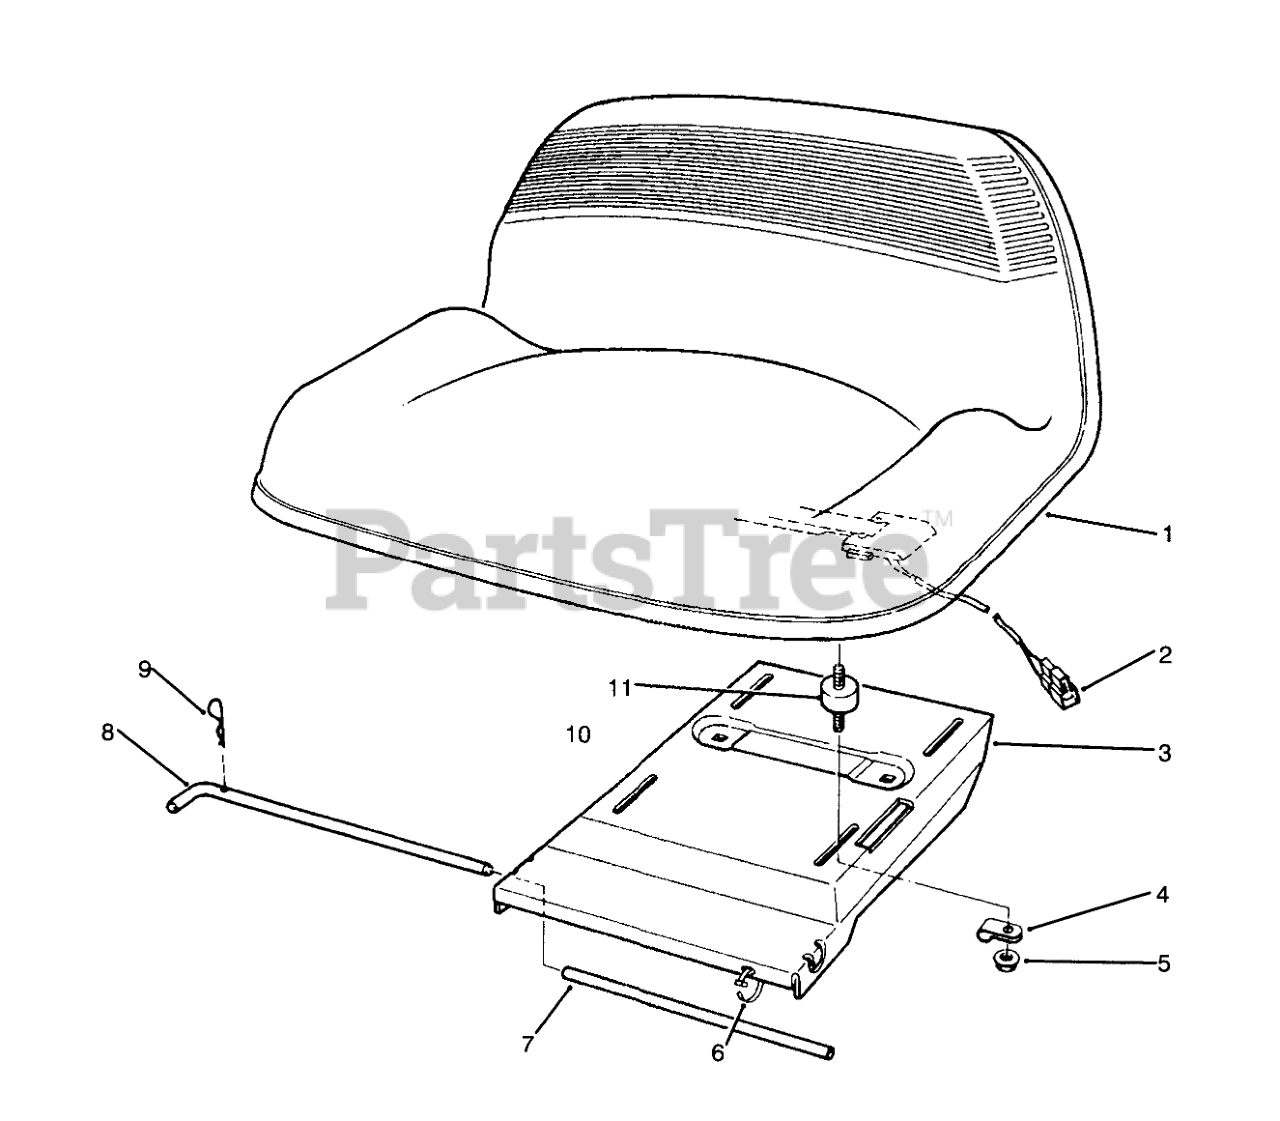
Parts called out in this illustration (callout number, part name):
1	SEAT
2	SWITCH-SEAT
3	Base-Seat
4	CLAMP
5	NUT-HF
6	TIE-CABLE
7	TUBE-SEAT
8	ROD-SEAT BASE
9	PIN-COTTER
11	ISOLATER-SEAT
